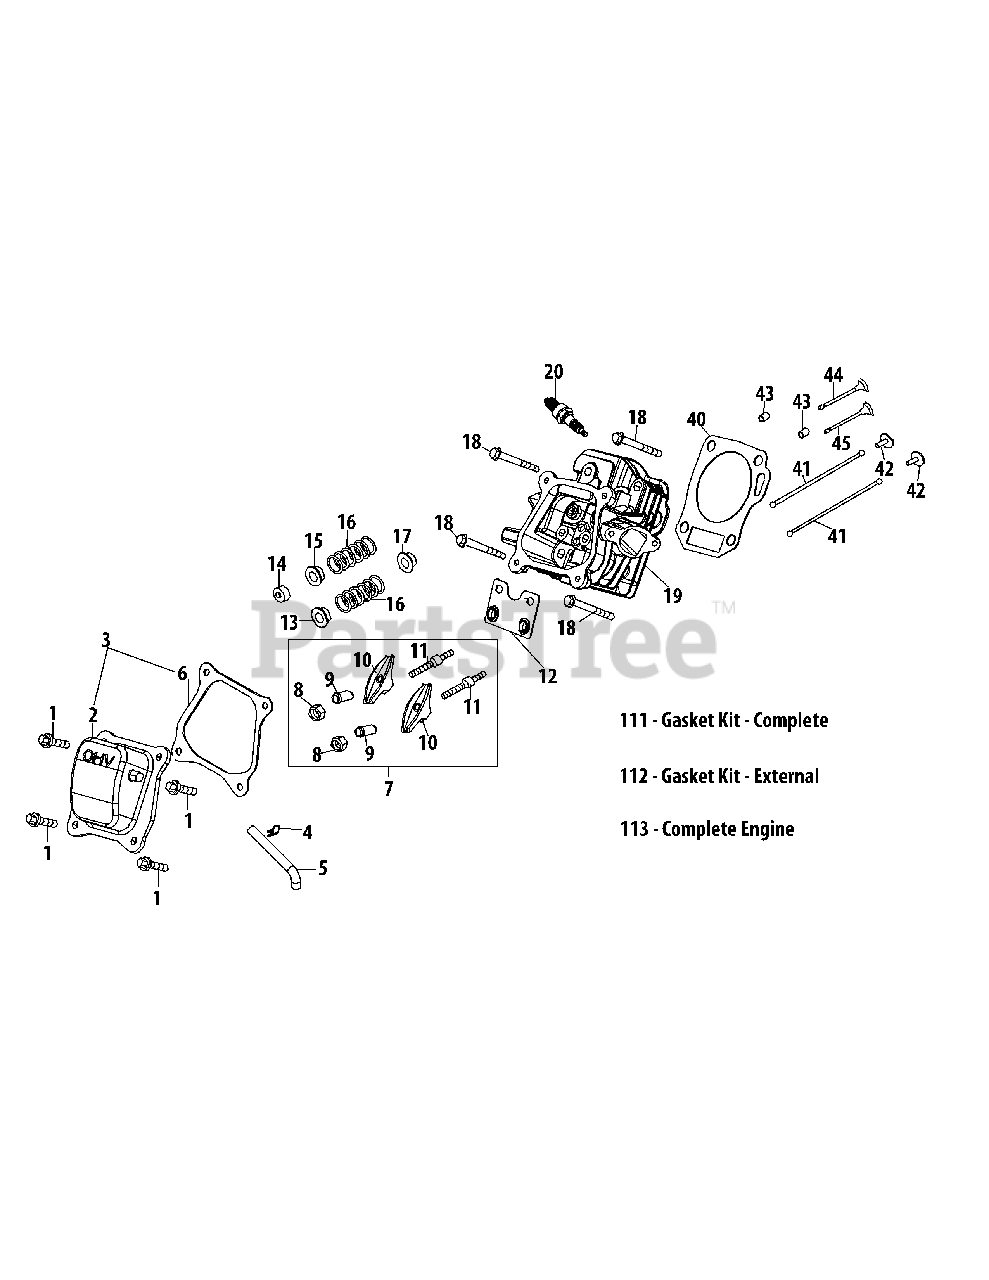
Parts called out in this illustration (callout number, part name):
1	Bolt M6×16
2	Valve Cover
3	Valve Cover Kit
4	Breather Hose Clamp
5	Breather Hose
6	Valve Cover Gasket
7	Rocker Arm Assembly
8	Nut, Pivot Locking
9	Adjusting Nut, Valve
10	Rocker Arm
11	Bolt, Pivot
12	Push Rod Guide
13	Valve Spring Retainer (Intake)
14	Exhaust Lash Cap
15	Valve Spring Retainer (Exhaust)
16	Valve Spring
17	Valve Seal (Intake)
18	Bolt M8×55
19	Cylinder Head Assembly
20	Spark Plug/F6Rtc
40	Gasket, Cylinder Head
41	Push Rod Kit
43	Dowel Pin 10×16
111	Gasket Kit - Complete
112	Gasket Kit - External
113	Complete Engine
